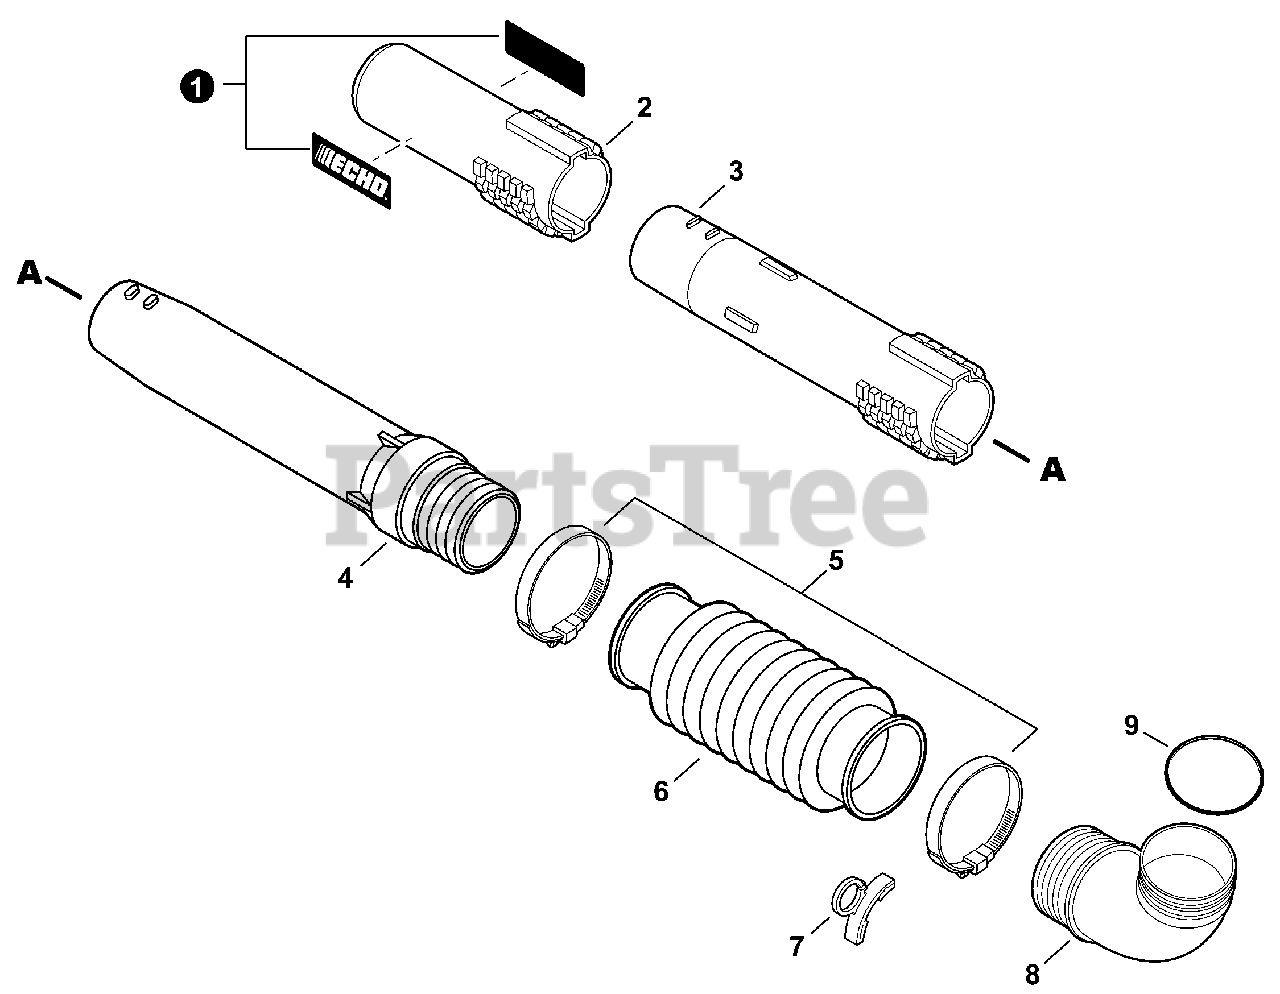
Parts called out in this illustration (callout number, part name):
1	LABEL, ECHO BLOWER TUBE
2	TUBE, NOZZLE 318×72/91
3	TUBE, BLOWER - STRAIGHT
4	TUBE, BLOWER - SWIVEL
5	CLAMP 77.8MM /101.6MM
6	TUBE, BLOWER - FLEXIBLE
7	CLIP, CABLE
8	TUBE, BLOWER - ELBOW
